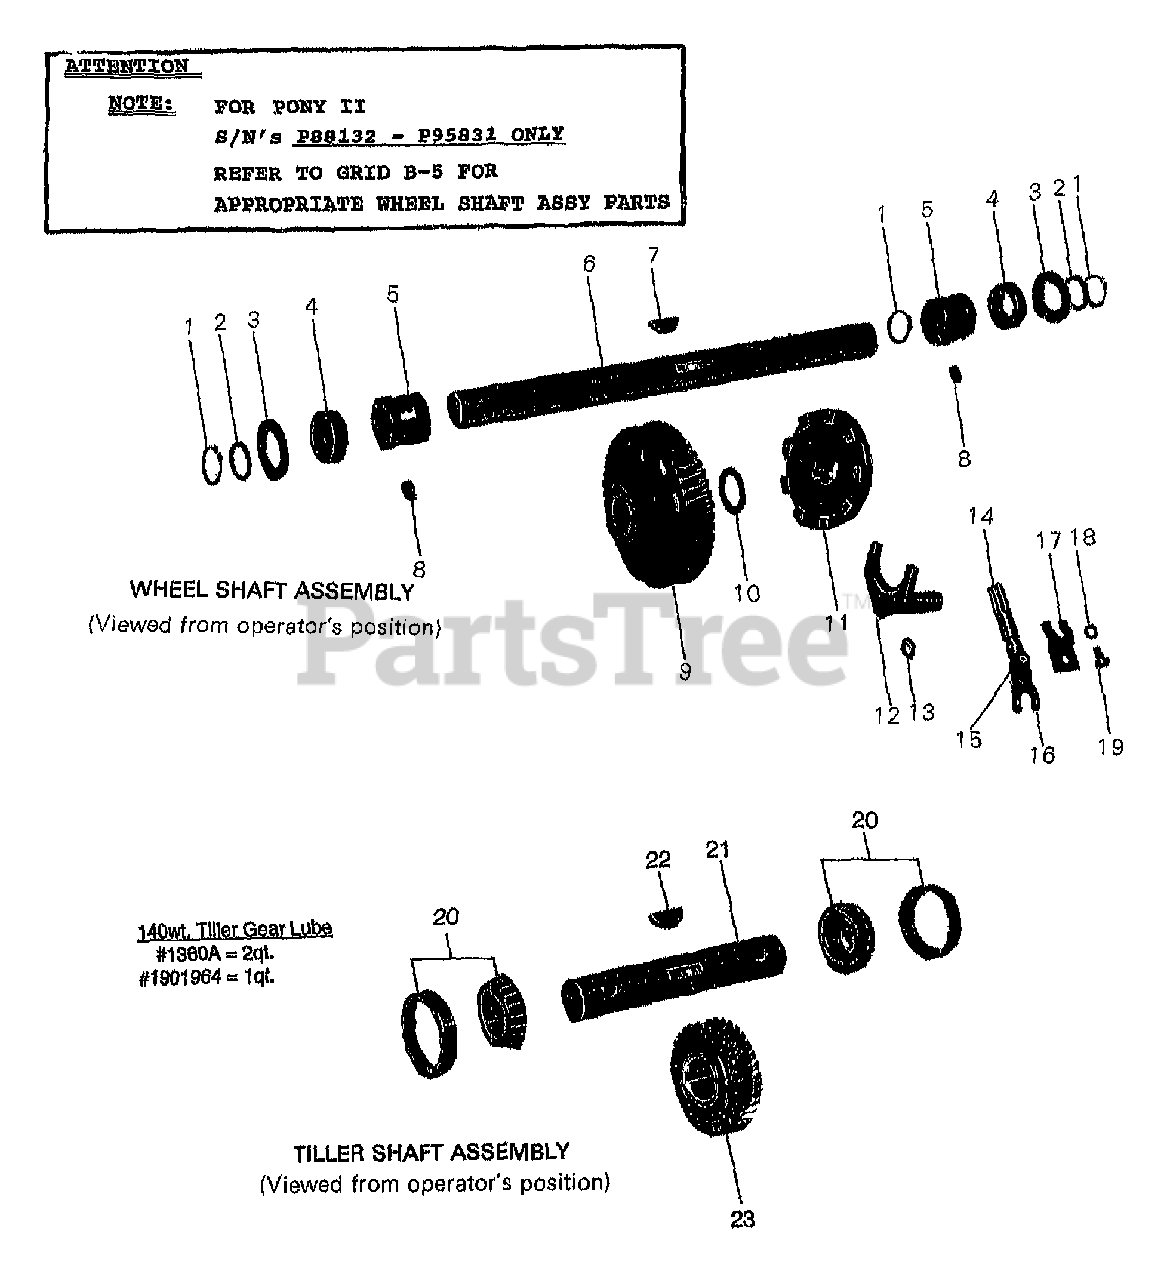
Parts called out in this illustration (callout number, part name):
1	RING-RETAINING 5100-100
2	SHIM SET-WHEELSHAFT-HORSE
2	SHIM-1.375X1.015X.03
2	SHIM-1.375X1.015X.015
2	SHIM-1.375X1.015X.01
3	SHIM-1.75X1.013X.09
4	SEAL-OIL WHEELSHAFT
5	BUSHING-1.503X1.005X1.187
6	ASSM-WHEELSHAFT W/KEY (REPLACES # 20322)
7	KEY-HI PRO .25X1.062
8	SCR-SS 3/8-16 X .5 (CP)
9	GEAR-WORM
10	SHIM-1.375X1.015X.062
11	CLUTCH-MACH
12	YOKE-RIVETED HT
13	RING-O .625 X .438
14	SPLINE/YOKE-HT
15	PIN-SPIROL .188 X .875
16	UNIVERSAL (U-JOINT)
17	PLATE-FRICTION
18	WASHER-LK .25 ZP
19	SCR-HH 1/4-20X.5 GR5 YEL
20	BRG & RACE
21	ASSM-TILLERSHAFT W/KEY (REPLACES #20335)
22	KEY-WOODRUFF .25X1.12
23	KIT-TILLER GEAR PONY 1-4
